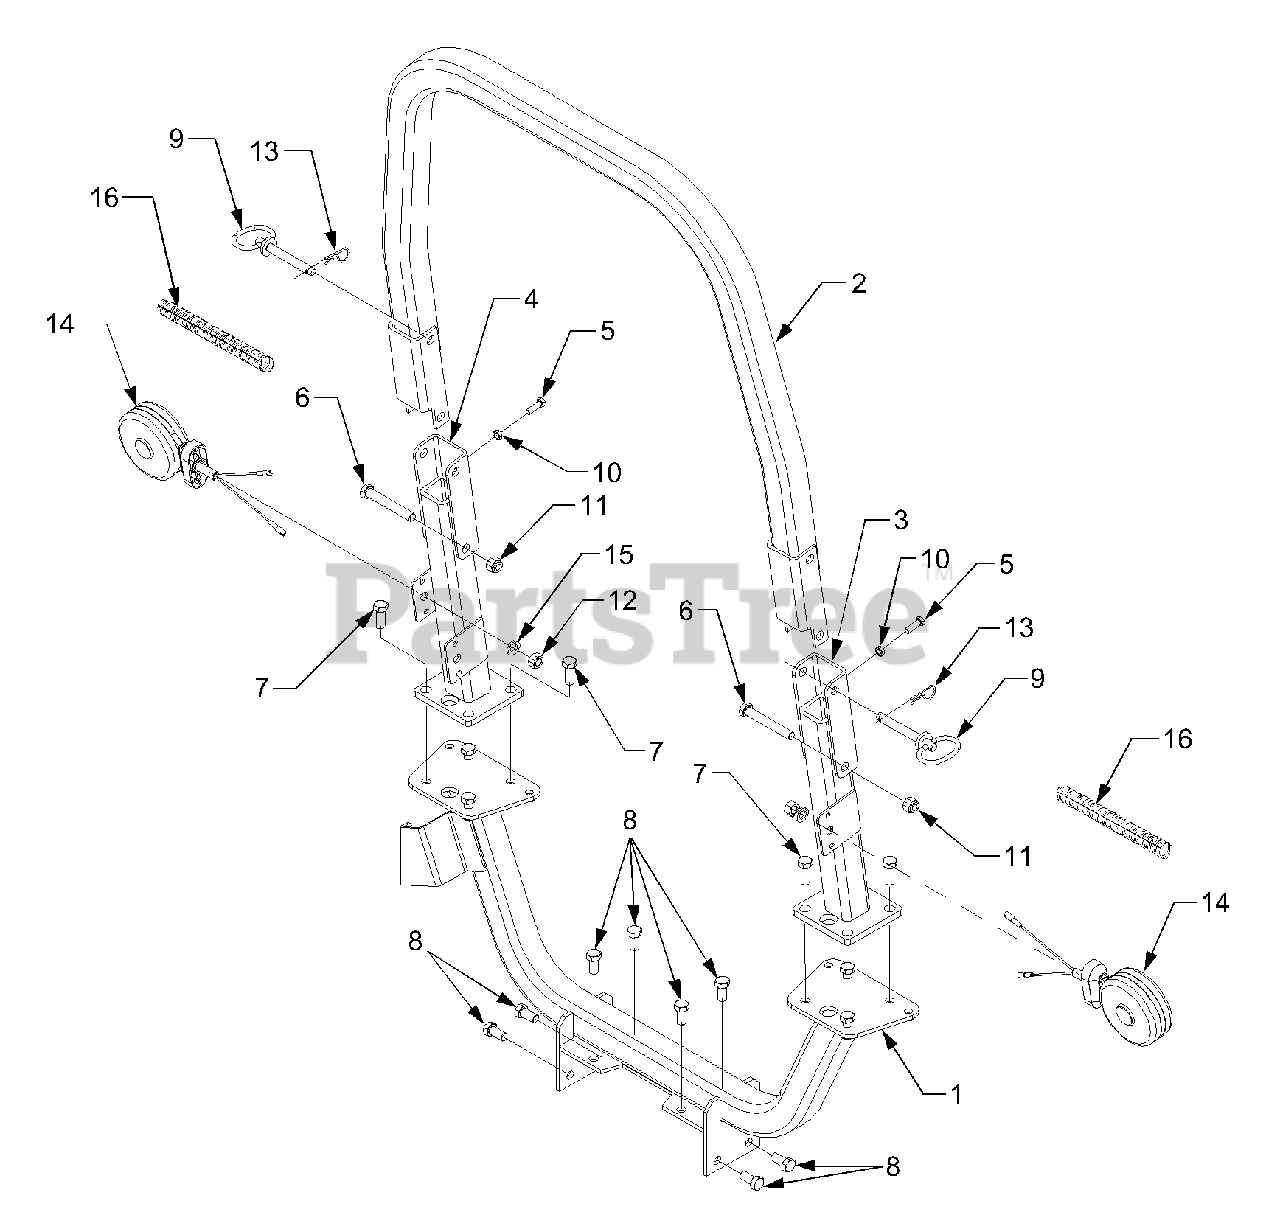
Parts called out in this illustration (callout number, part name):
1	ROPS Assembly, Lower
2	ROPS Assembly, Upper
3	Mounting Assembly, ROPS RH
4	Mounting Assembly, ROPS LH
5	Screw, Hex Cap, 5/16-18 x 1.0 GR5
6	Screw, Hex Cap, 1/2-20 x 3.5 GR5
7	Screw, Hex Cap, 1/2-13 x 1.25 GR5
8	Screw, Hex Cap, 1/2-13 x 1.0 GR5
9	Pin, Clevis, .5 x 3.5
10	Nut, Hex Jam, 5/16-18
11	Nut, Hex Nylon Insert Lock, 1/2-20
12	Nut, Hex, 1/2-20 GR5
13	Pin, Internal Cotter
14	Light Assembly, Hazard
15	Washer, Lock, 1/2
